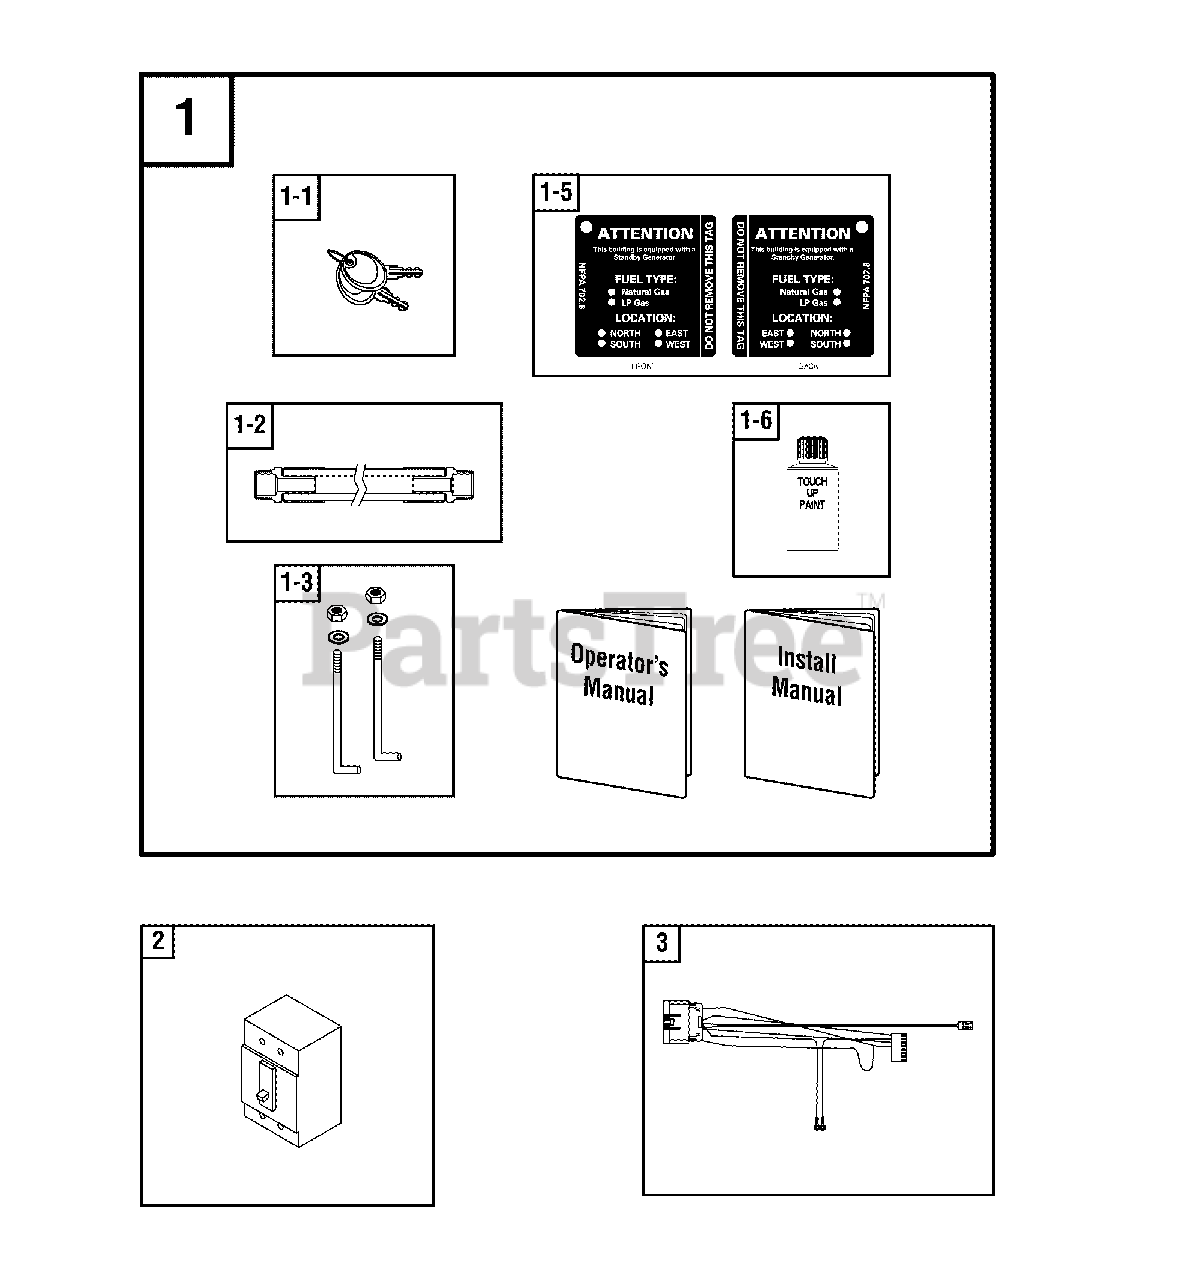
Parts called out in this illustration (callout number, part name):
1	KIT-MANUAL ACC
1-3	KIT-HARDWARE BATTERY
1-5	HANG TAG-ATTN. STANDBY EQUIPMENT
1-6	PAINT, TOUCH-UP, CONT CHARCOAL, TEXTURE
2	BREAKER-CIRCUIT
